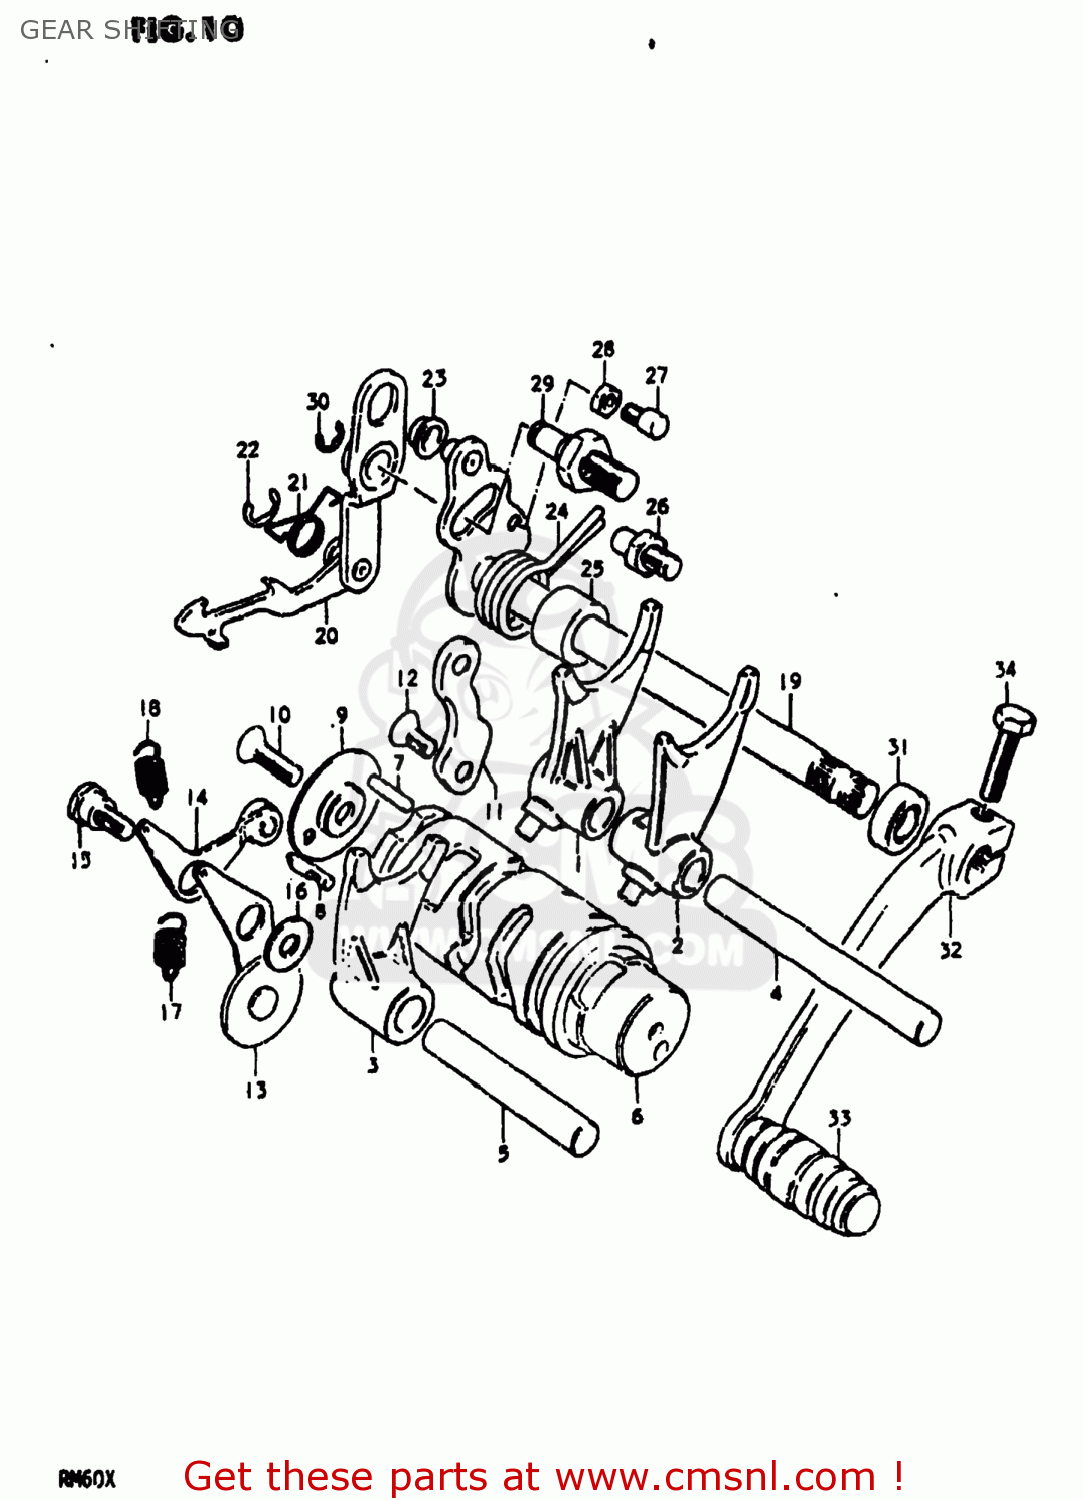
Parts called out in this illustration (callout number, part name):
1	FORK,GEAR SHIFT NO.1
2	FORK,GEAR SHIFT NO.2
3	FORK,GEAR SHIFT NO.2
4	SHAFT,GEAR SHIFT FORK
5	SHAFT,GEAR SHIFT FORK
6	CAM,GEAR SHIFT
7	PIN(4X15.8)
8	PIN
9	RETAINER,GEAR SHIFT CAM
10	SCREW
11	GUIDE,GEAR SHIFTING CABLE
12	SCREW
13	STOPPER,GEAR SHIFTING
14	STOPPER,GEAR SHIFT CAM
15	BOLT(6X18.3)
16	WASHER (6.5X13X2.3)
17	SPRING
18	SPRING
19	SHAFT,GEAR SHIFT
20	PAWL,GEAR SHIFT
21	SPRING
22	E RING
23	SPACER(7X10X5)
24	SPRING
25	SPACER(12X20X15.3)
26	STOPPER,GEAR SHIFT CAM
27	BOLT,GEAR SHAFT RETURN SPR SET
28	NUT 6MM
29	STOPPER,GEAR SHIFT CAM
30	WASHER 6MM
31	OIL SEAL
32	LEVER ASSEMBLY,GEAR SHIFTING
33	RUBBER,GEAR SHIFT PEDAL
34	BOLT
